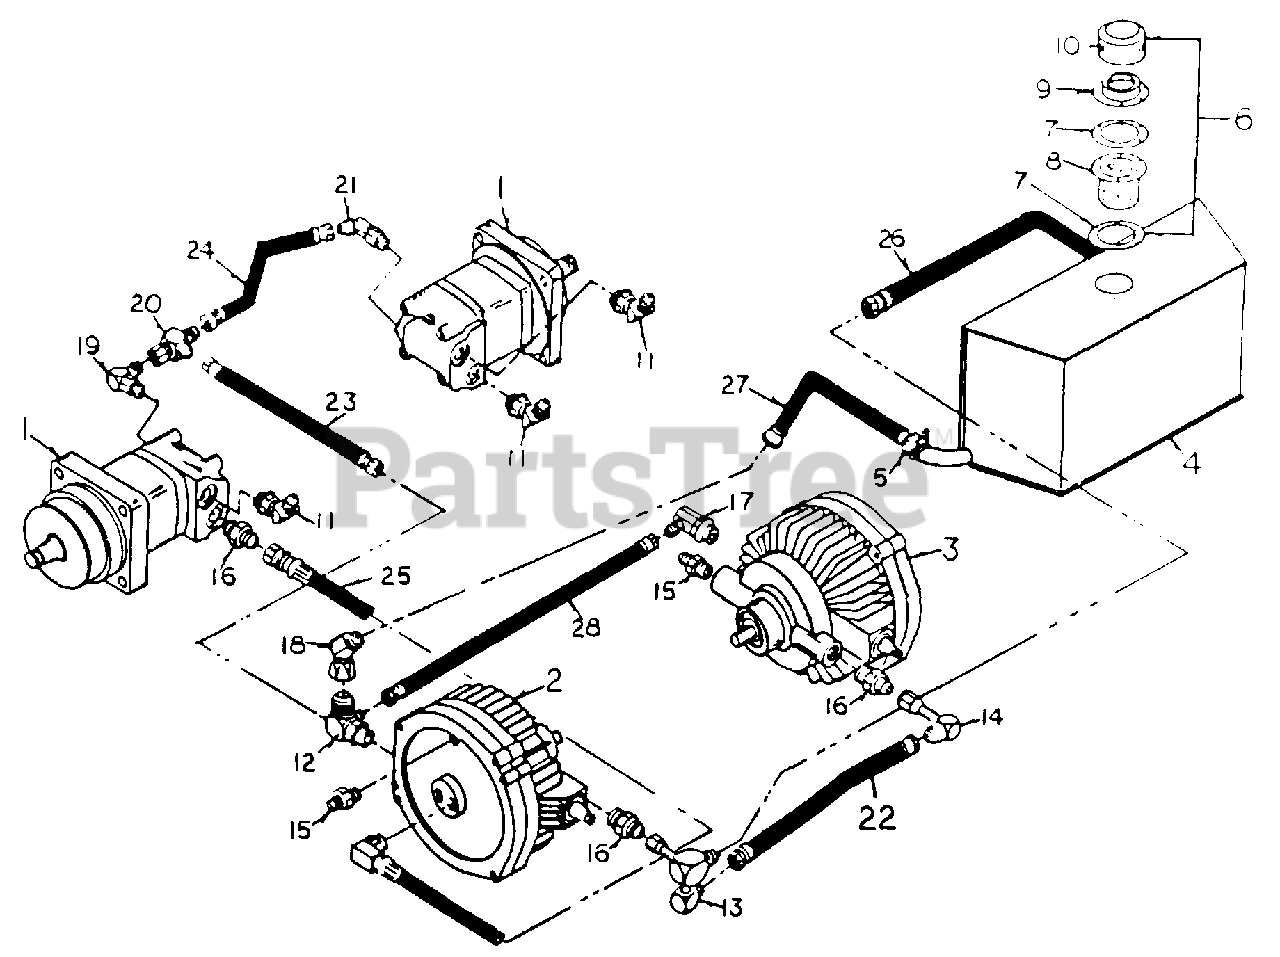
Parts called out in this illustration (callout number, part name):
3	PUMP - R.H.
4	HYDRAULIC OIL TANK
5	HOSE CLAMP
6	HYDRAULIC FILL CAP ASSEMBLY
8	STRAINER
9	FILL NECK
11	MALE TUBE - 45° male o-ring adapter
12	FITTING - special cross
13	SPECIAL ADAPTER
14	FITTING - male tube, 90° female swivel adapter
15	FITTING - male tube, male o-ring adapter
16	FITTING - male tube, male o-ring adapter
17	FITTING - male tube, 90° male o-ring adapter
18	FITTING - male tube, 45° female swivel adapter
19	FITTING - male tube, 90° male o-ring adapter
20	FITTING - male tube, female swivel tee
21	FITTING - male tube, 45° female swivel adapter
22	HOSE - 1/2" ID x 18" long, easy couple
23	HOSE - 1/4" ID x 14" long, easy couple
24	HOSE - 1/4" ID x 20" long, easy couple
25	HOSE - 1/2" ID x 36 1/2" long
26	HOSE - 3/4" ID x 22" long, easy couple
27	HOSE - 3/4" ID x 18" long, easy couple
28	HOSE - 1/2" ID x 20" long, easy couple
